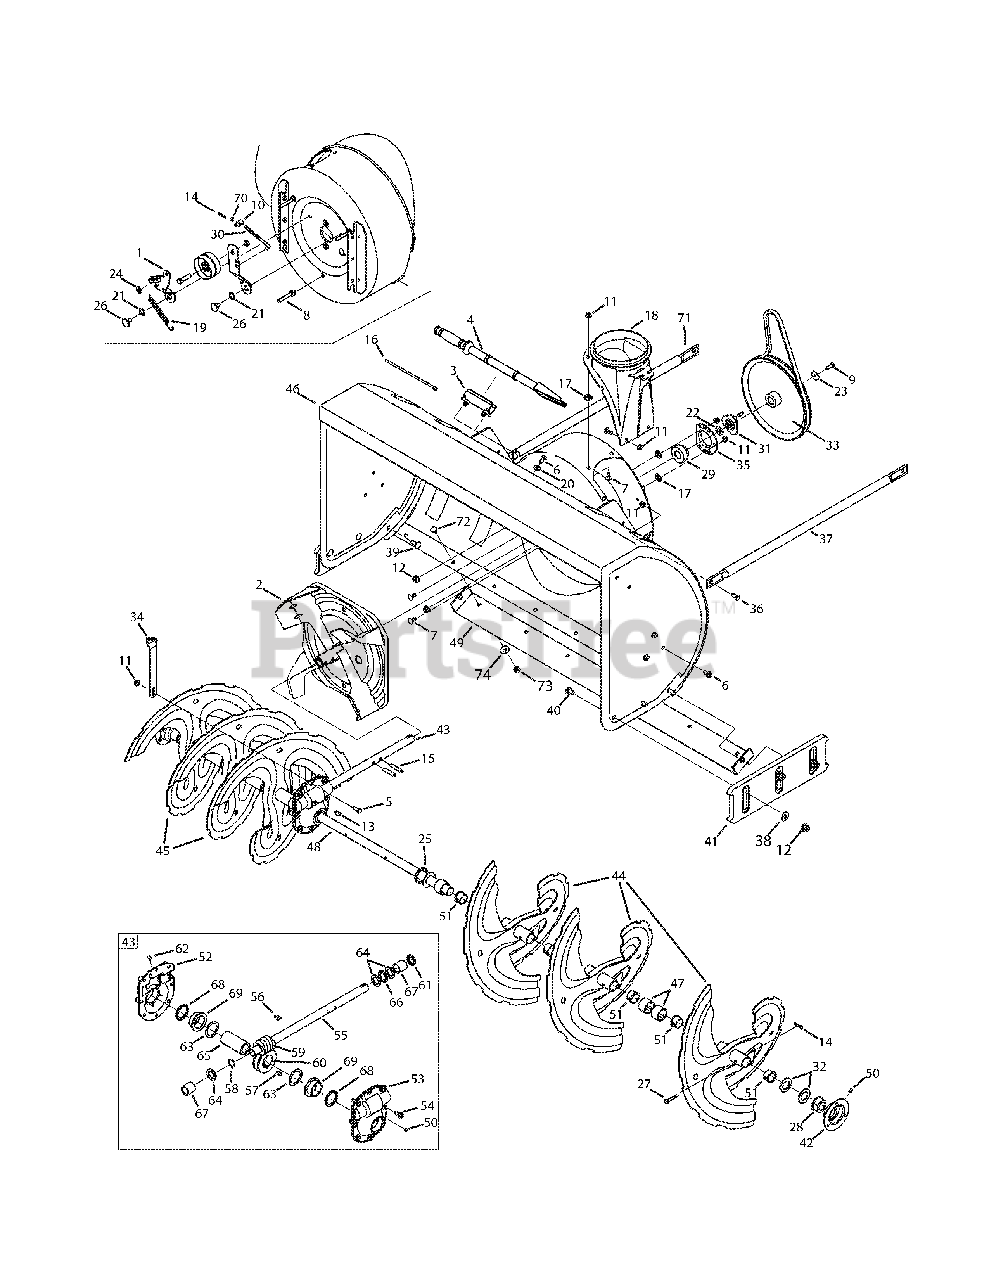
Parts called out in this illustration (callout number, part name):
1	Bracket Assembly, Auger Brake
2	Impeller, 16"
3	Clip, Mounting
4	Tool, Clean-out
5	Screw, Hex Cap, 5/16-18 x 1.0 Gr5
6	Screw, 5/16-18 x .750
7	Screw, Carriage, 5/16-18 x .75
8	Screw w/Stud, 5/16-18 x .4300
9	Screw, Hex Cap Lock, 5/16-24, 875
11	Nut, Hex Flange Lock, 5/16-18
12	Nut, Hex Flange Lock, 3/8-16
13	Key, Woodruff, 1/4 x 3/4
14	Pin, Bow-tie Cotter
15	Pin, Spiral, 5/16 x 1.75
16	Cable Tie
17	Nut, Push
18	Adapter, Chute, 6"
19	Spring, Extension
20	Washer, Flat, .349 x .879 .063
21	Washer, Wave, .625 x .885 x .015
22	Washer, Bell., .78 x 1.49 x .06
23	Washer, Flat, .34 x 1.5 x .15 Ht.
24	Washer, .344 x .75 x .12
25	Washer, 1.01 x 1.86 x .06
26	Screw, Shoulder, .625 x .17
27	Pin, Shear, .25 x 1.75
28	Bearing, Flange w/Flats
29	Bearing, Self Aligning
30	Rod, Auger Idler
31	Adapter, Pulley w/Pins
32	Spacer, 1.004 x 1.375 x .25
33	Pulley, Auger Drive, 10.0
34	Bracket, Gear Box Support
35	Housing, Bearing
36	Screw, 5/16-18 x .75 GR5
37	Tube, Support , LH
38	Washer, Flat, .385 x .870 x .092
39	Screw, Carriage, 3/8-16 x .75
40	Screw, Carriage, 3/8-16 x 1.00
42	Housing, Bearing
43	Gear Box Assembly
44	Spiral Assembly, LH
45	Spiral Assembly, RH
46	Housing, Auger - 45"
47	Spacer, 1.50 x 1.00 x 1.00
48	Axle, Spiral
49	Shave Plate, 45"
50	Grease Fitting, 3/16
51	Flange Bushing
52	Housing Assembly, Auger, RH
53	Housing Assembly, Auger, LH
54	Screw, LD, 5/16-18 x .750
55	Auger Drive Shaft
56	Key, Hi Pro, 3/16 x 3/4
57	Key, 1/4 x 3/4 Dia.
58	External Retainer Ring
59	Gear, Worm
60	Gear, Worm, LH
61	Seal, Oil
63	Wash, Flat, 1.52ID x 2.0 OD
64	Wash, Flat, .88 ID x .38 OD
65	Worm Gear Shaft
66	Bearing, Thrust
69	Flange Bearing
70	Jam Nut, 5/16-18
71	Tube, Support, RH
72	Screw, Carriage, 5/16-18 x .750
73	Nut, Hex, 5/16-18
74	Washer, Bell., .34 x .872 x .060
